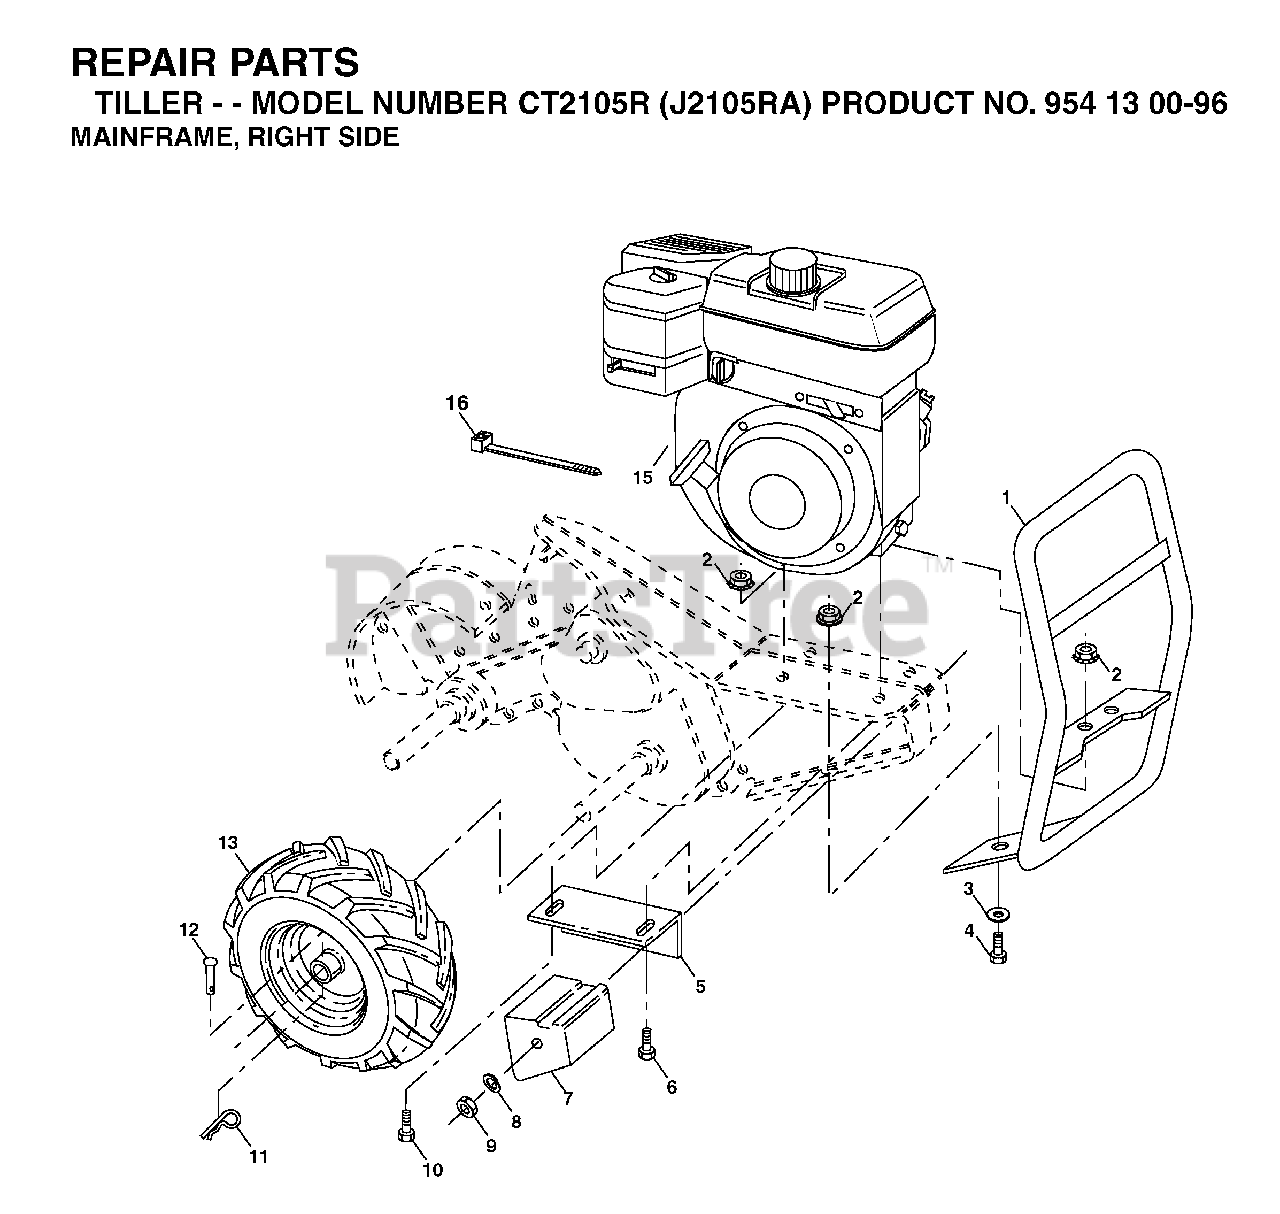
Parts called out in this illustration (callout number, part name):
1	BUMPER.ASM.TILLER.
2	LOCKNUT-FLANGE 5/16-18
3	WASHER
4	BOLT
5	BRACKET RH CRT
7	COUNTERWEIGHT, RH
8	WASHER, LOCK 3/8
9	NUT.HEX.3/8-16UNC
10	BOLT
11	RETAINER M
12	RIVET,DRILLED
16	TIE GUIDE
5321243-66	RIM
5321247-18	VALVE STEM LT
